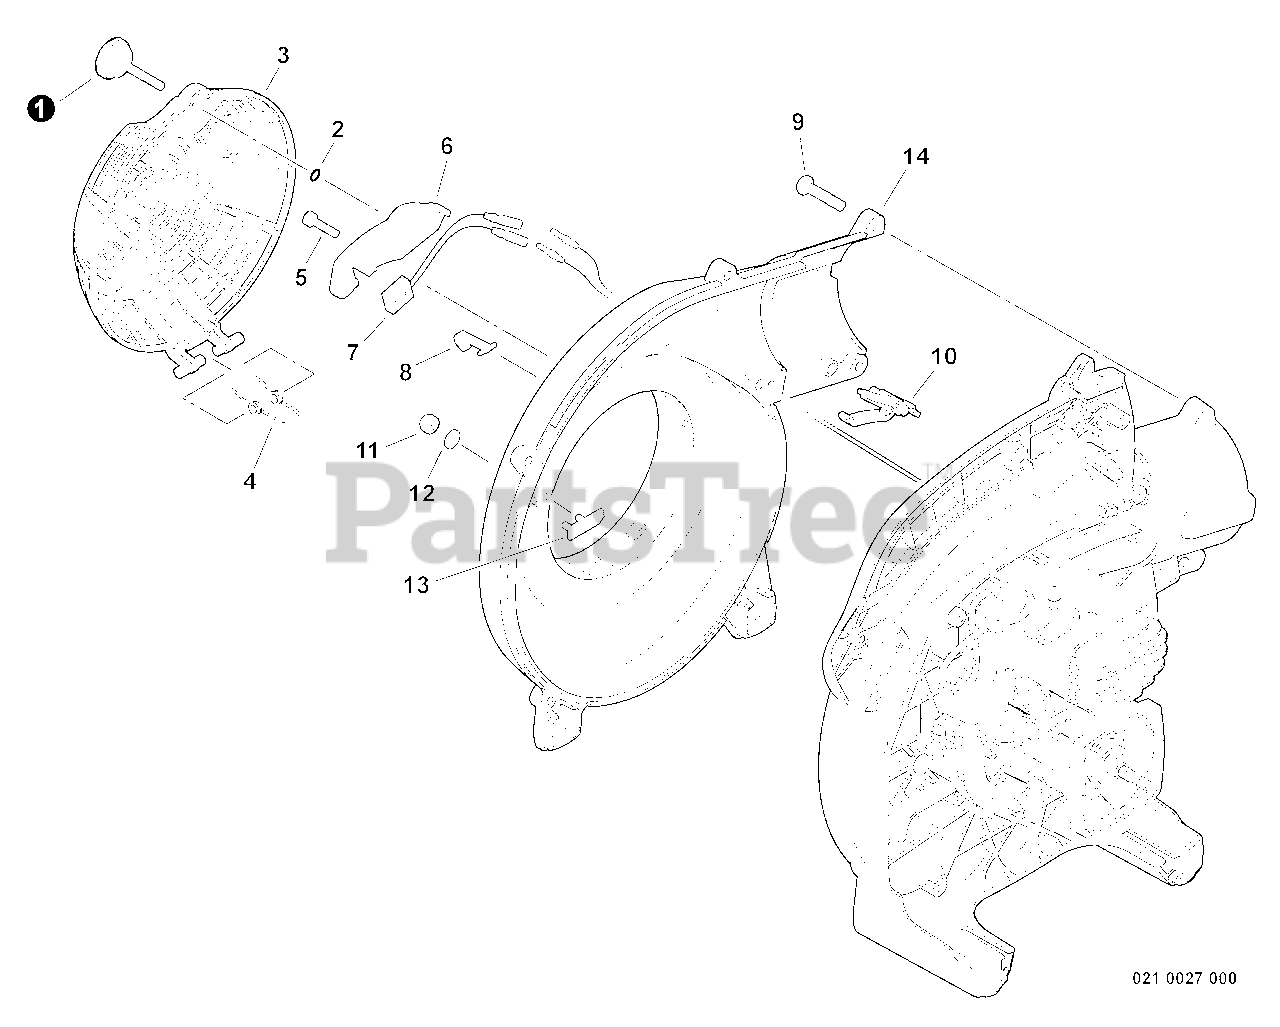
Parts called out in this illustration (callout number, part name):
1	THUMBSCREW
2	O-RING - 3
3	GUARD, DEBRIS
5	SCREW - 4X16 -- TAPPING
6	COVER, SWITCH
7	SAFETY SWITCH ASSY
8	LEVER, ACTUATOR
9	SCREW - 5X20
10	LOCK, TUBE
11	LOCKNUT - 5
12	WASHER - 5
14	COVER, FAN - LEFT
